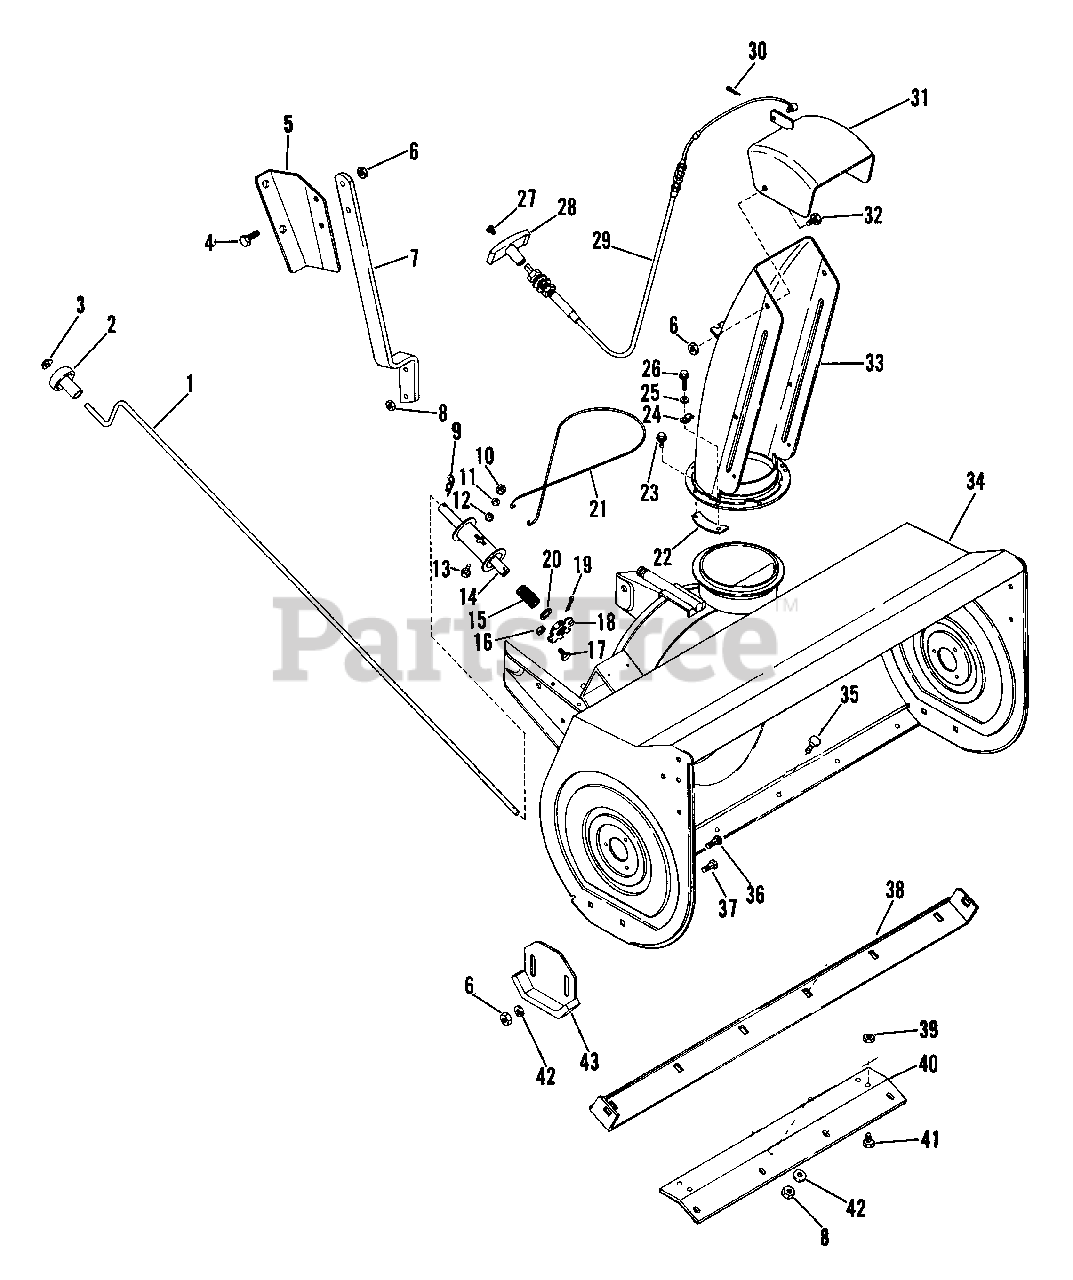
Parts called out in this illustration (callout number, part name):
1	CHUTE CONTROL CRANK
3	RG-RTNG-EXT .500X.015
4	BLT-HEX .38-16X1.00 PL
5	CONTROL BRACKET
6	NUT-LK-CTR .375-16 GR A PL
7	CHUTE CRANK SUPPORT
8	NUT-LK .312-18 GR A PL
9	PIN-HAIR INT .08X.38X1.42 YWZC
10	NUT-HEX .250-20 PL
11	WSHR-LK .313X.062
12	WSHR-FL-STL.281X.62X.065 PL
13	BLT-RDHDSQNK .25-20X.62 PL
14	SPOOL
15	SG-COMP .054X.75X1.6
16	NUT-LK DUAL FACE 10-24 PL
17	SCR-SKH 10-24X.38
18	DISC ASSEMBLY
19	PIN-ROLL .188X1.00
20	WSHR-FL-STL .640X1.005X.062 PL
22	CHUTE CLAMP
23	SCR-TAP 10-24X.375 CRPH PL 1A
24	CABLE CLAMP
25	WSHR-FL-STL .188X.438X.049 PL
26	SCR-TAP 10-24X.75 CRPH 1A
27	SCR-MCH 10-32X.50 SLPAN SS
28	TEE HANDLE
29	CONTROL CABLE
30	PIN-COTR .09X.75 PL
31	DEFLECTOR W/DECAL
32	BLT-HEX .38-16X.75 PL GR2
33	DISCHARGE CHUTE
34	36 IN SNO-THRO HOUSING WITH DE
35	BLT-RDHDSQNK .31-18X.75 SHT PL
36	BLT-RDHDSQSHNK .38-16X1.00 PL
37	BLT-RDHDSQNK .38-16X.75 SHT PL
38	SCRAPER BLADE 36"
39	NUT-LK TOP .375-16 GR C YWZC
40	BLADE BRACE
41	BLT-HEX .38-16X.75 PL GR5
42	WSHR-FL-STL .38X.875X.083 PL
43	RUNNER-SKID SHOE
